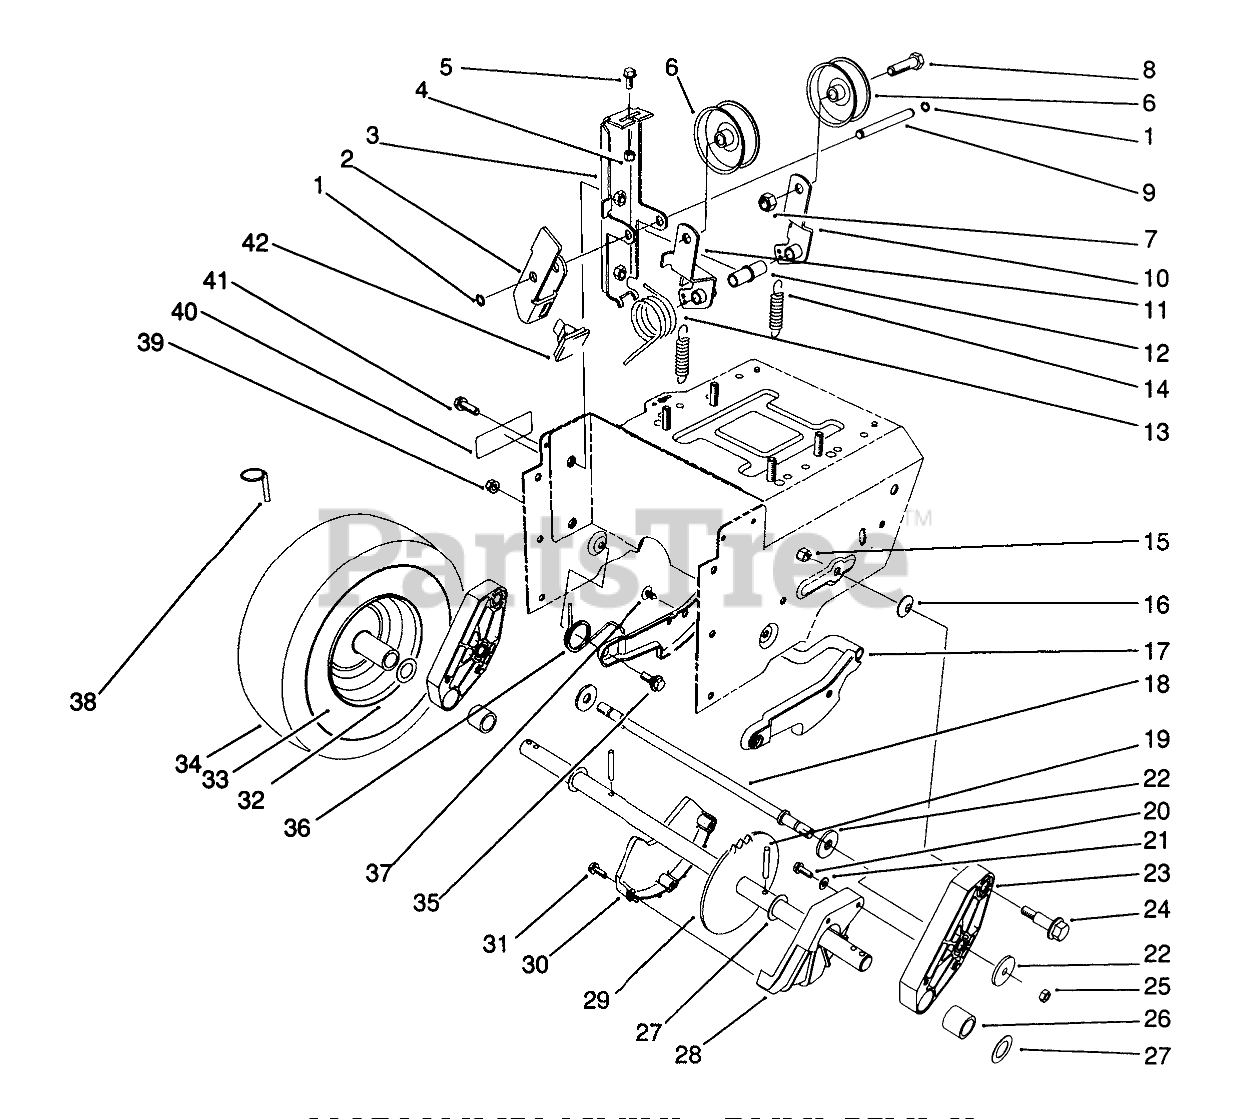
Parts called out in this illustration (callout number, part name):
1	RING-RETAINING
2	ARM-BRAKE
3	IDLER ARM BRACKET ASM
4	NUT-LOCK, NI
5	SCREW-HHF
6	PULLEY-IDLER
7	NUT-LOCK, NI
8	SCREW-HH
9	PIN-IDLER
10	ARM-IDLER, TRACTION
11	ARM-IDLER, IMPELLER
12	BUSHING-IDLER
13	TORSION SPRING
14	SPRING-EXTENSION
15	NUT-LOCK, NI
16	WASHER-SPRING
17	Latch-Arm
18	ROD-LATCH
19	PIN-ROLL, SLOTTED
20	SCREW-HWH
21	WASHER-FLAT
22	WASHER-SUPPORT
23	Pivot Arm Assembly (Incl. Ref. #26)
24	BOLT-SHOULDER
25	NUT-LOCK, NI
26	BUSHING-AXLE
27	WASHER-THRUST
28	GUARD-CHAIN, LH
30	GUARD-CHAIN, RH
31	Screw
32	RIM-WHEEL
33	INNER TUBE
35	SCREW-SHOULDER
36	SPRING-LATCH, TORSION
37	FASTENER-PANEL
38	PIN-LYNCH
39	NUT-LOCK, NI
40	DECAL-WARNING
41	SCREW-HHF
42	PAD-BRAKE
